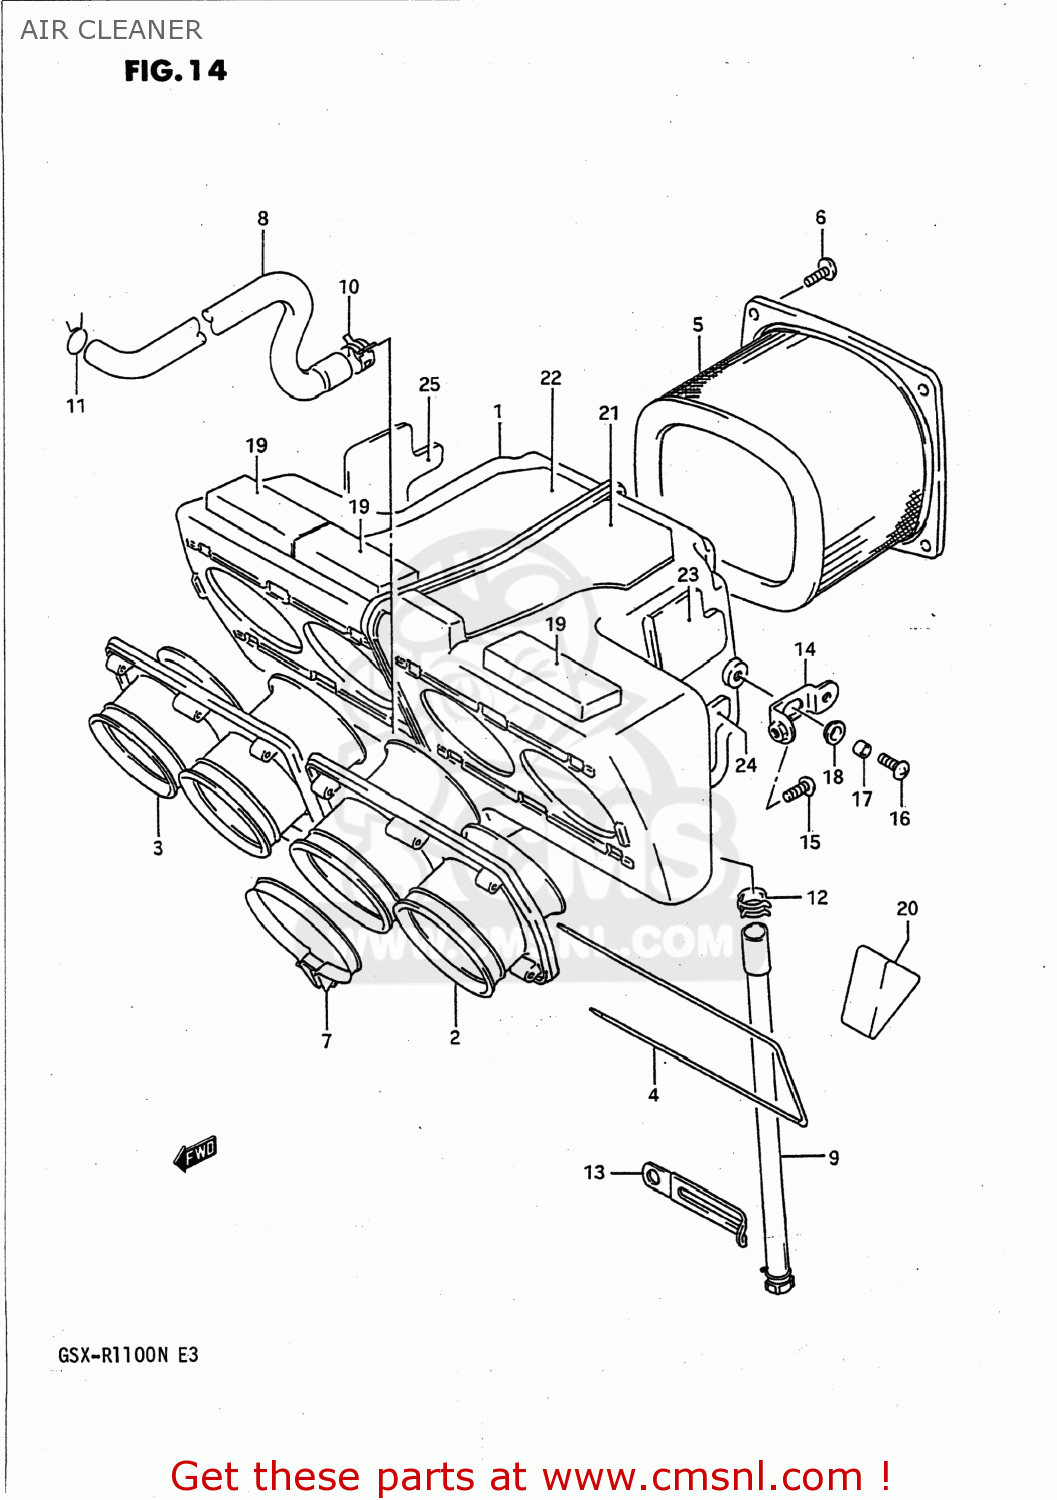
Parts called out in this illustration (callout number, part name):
1	CASE,AIR CLEANER
2	TUBE,AIR CLEANER OUTLET LH
3	TUBE,OUTLET,R
4	SHAFT,OUTLET TUBE
5	FILTER ASSY,AIR CLEANER
6	SCREW
7	CLAMP
8	TUBE,BREATHER
9	DRAIN TUBE
10	CLIP
11	CLIP
12	CLIP
13	CLAMP
14	BRACKET,AIR CLEANER CASE
15	SCREW
16	SCREW(6X18)
17	SPACER
18	WASHER
19	CUSHION,AIR CLEANER CASE
20	CUSHION,AIR VENT HOSE
21	SHEET,AIR CLEANER NO.1
22	SHEET,AIR CLEANER NO.2
23	SHEET,AIR CLEANER NO.3
24	SHEET,AIR CLEANER NO.4
25	SHEET,AIR CLEANER NO.5
